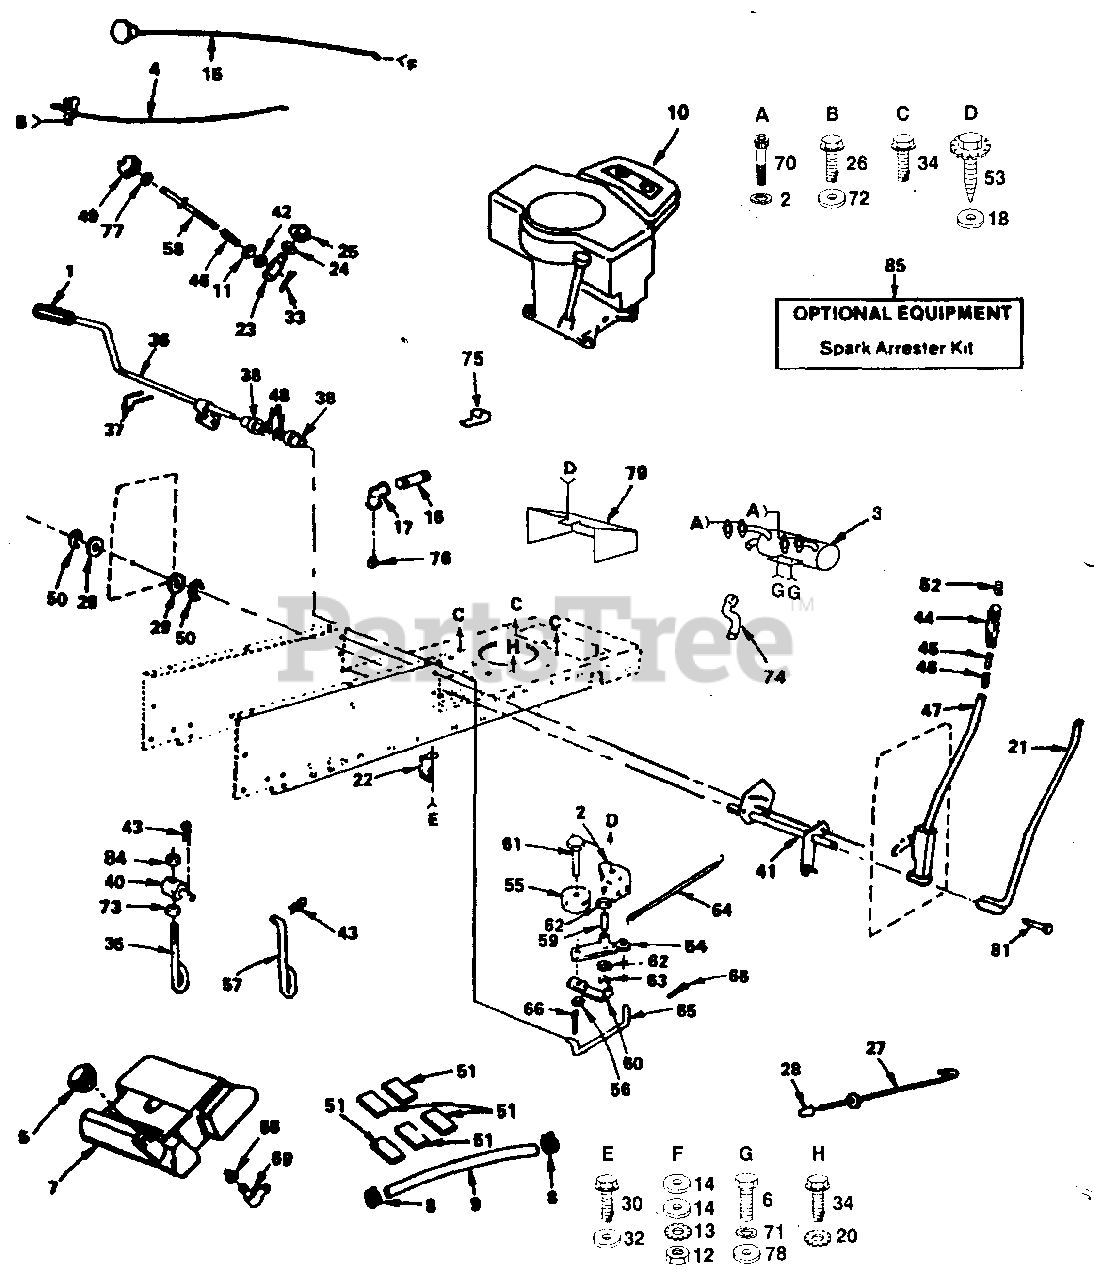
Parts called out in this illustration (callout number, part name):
1	Cover, Pedal
2	Washer, Lock, Heavy Helical Spring
4	Control, Throttle
5	Cap, Fuel
6	Bolt, Fin. Hex 1/4-20 x 5/8
10	Engine, Kohler
11	Washer 13/32 x 5/8 x 16 Gauge
12	Nut, Hex 3/8-24
13	Washer, Lock, External Tooth 3/8
14	Washer 13/32 x 13/16 x 16 Gauge
15	Control, Choke
16	Pipe Nipple, Standard
17	90ø Elbow 3/8 NPT
20	Washer, Lock, External Tooth 3/8
21	Rod Assembly, Lever
22	Retainer, Belt, Chassis, Center
23	Trunnion, Stop, Depth
24	Washer 15/32 x 3/4 x 16 Gauge
26	Screw, Hex Wsh. Hd., Thd. Cut. 1/4-20 x 1/2
27	Rod, Brake, Park
29	Washer 29/32 x 1-1/4 x 16 Gauge
30	Screw, Hex Wsh. Thd., Rolling 3/8-16 x 3/4
32	Washer 13/32 x 1-3/16 x 16 Gauge
33	Pin, Cotter 3/32 x 1/2
34	Screw, Hex Washer Head, Threaded, Rolling 3/8-16 x 1-1/2 Type TT
35	Lift, Link, Adjustable
36	Shaft, Pedal, Foot
37	Roll Pin 3/16 x 1
38	Bearing, Nylon
40	Trunnion, Lift
41	Shaft Assembly, Lift
42	Nut, Hex, Special
43	Retainer, Spring
44	Grip, Handle
45	Plunger, Lever Lift
46	Spring
47	Lever Assembly, Hand Kit
48	Washer 21/32 x 1 x 16 Gauge
49	Handle, Adjust, Lift
52	Button, Plunger
53	Screw, Spiderlock Hex Head #8-1/2 AB
54	Arm Assembly, Idler
55	Pulley, Idler
56	Nut, Crownlock 3/8-16
58	Rod, Adjust, Lift
60	Retainer, Belt
61	Bolt, Hex 3/8-16 x 1-1/2
62	Washer, Hardened
64	Spring, Return, Clutch
65	Link, Clutch
66	Pin, Cotter 1/8 x 3/4
68	Bushing
69	Stem, Tank, Fuel
70	Screw, Hex Socket Head 5/16-16 x 12 Gauge
71	Washer, Lock, Heavy Helical Spring 1/4
72	Washer 9/32 x 5/8 x 16 Gauge
73	Nut, Hex, Jam 7/16-20
74	Tube, Exhaust
75	Clamp, Muffler
77	Nut, Hex, Jam 3/8-16
78	Washer 9/32 x 3/4 x 16 Gauge
81	Bolt, Hex 3/8-16 x 1-1/2
84	Nut, Crownlock 7/16-20
85	Spark Arrester Kit
